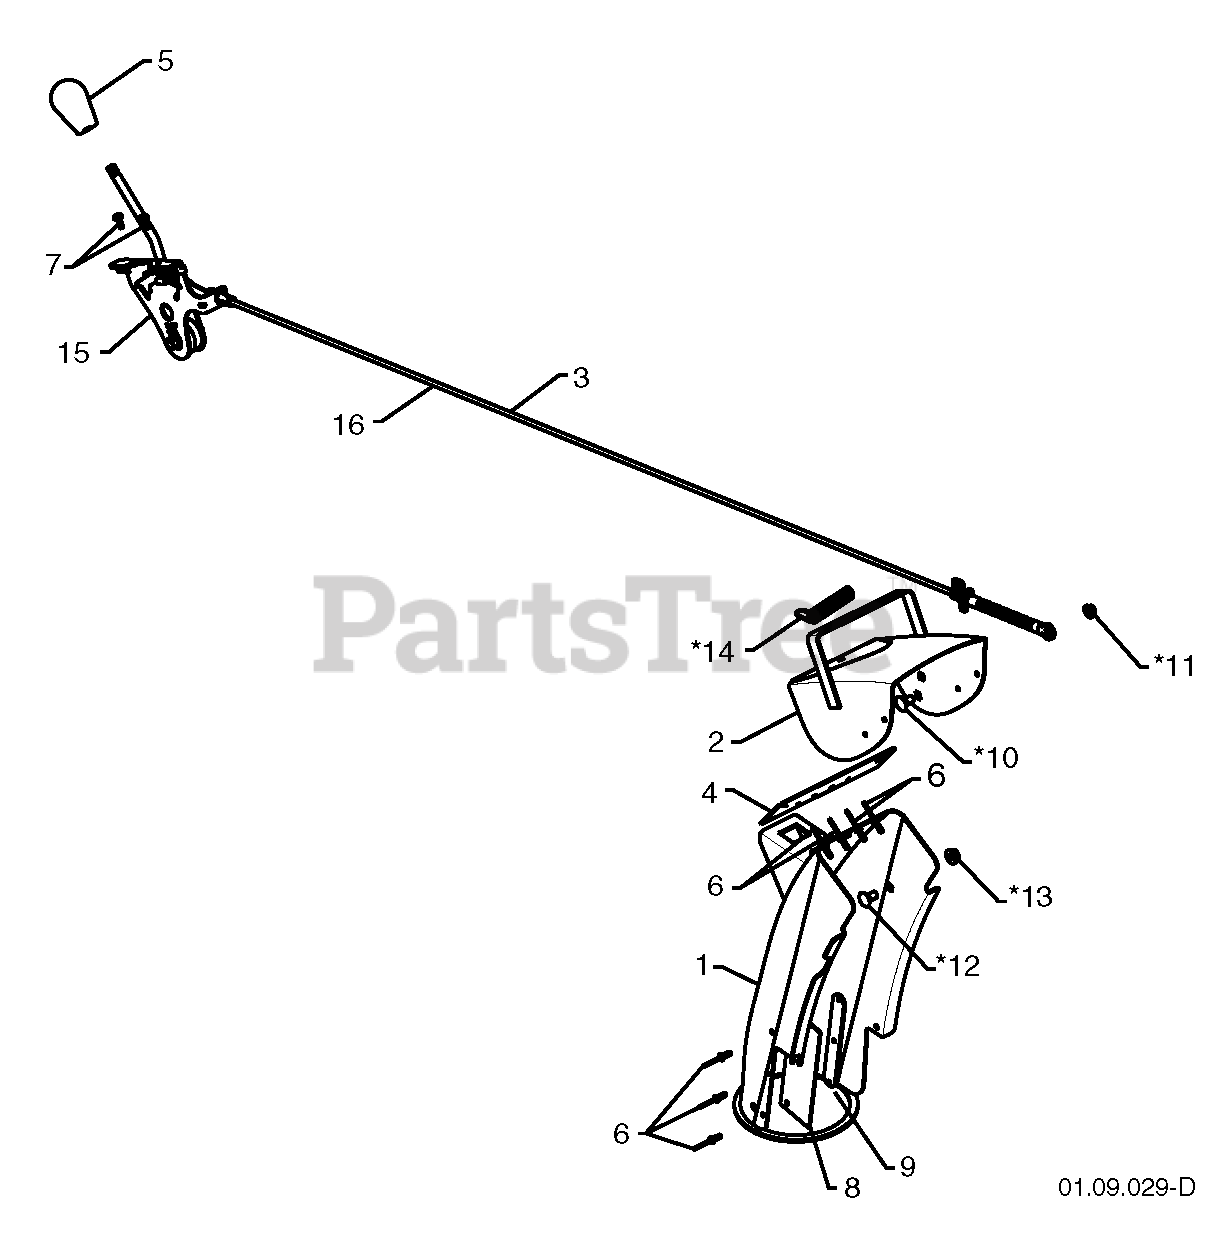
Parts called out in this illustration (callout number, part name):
1	ASM.CHUTE/DEFLECTOR.668
3	CONTROL.ASM.DEFLEC.BLK.BOWDEN
5	KNOB.OVERMOLD.DS.HUSQVARNA/BLK
10	BOLT, SHOULDER
11	NUT.HEX.FLANGE.1/4
12	BOLT CAR BLK 5/16-18 X 5/8
13	NUT.LOCK.5/16-18
14	SPRING.DEFLECTOR.REM.CHUTE
15	RP CNTRL.HEAD.ASSEM.DEFLECTOR
16	RP CABLE.DEFLECTOR.CONTRL.BOWD
